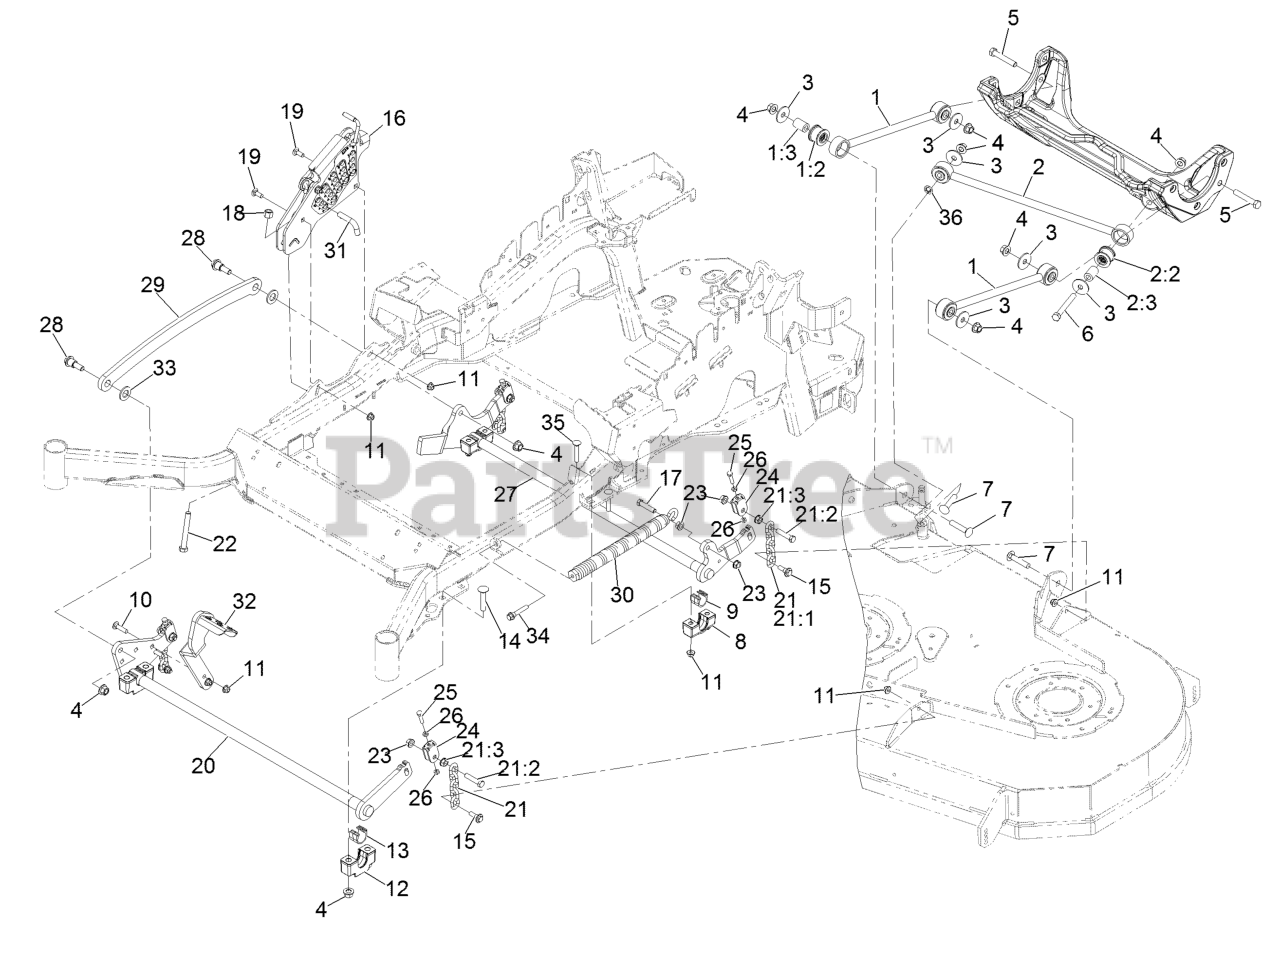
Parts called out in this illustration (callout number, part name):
1	DECK STRUT ASM
1:2	BUSHING-SUSPENSION, RUBBER
2	PANHARD ROD ASM
2:2	BUSHING-SUSPENSION, RUBBER
3	WASHER-THRUST
4	Nut-Lock 1/2-13
5	SCREW-HH
6	SCREW-HH
7	SCREW-CARR
8	SUPPORT-CROSS SHAFT, BEARING REAR
9	BEARING-CROSS SHAFT, REAR
10	SCREW-CARR
11	NUT-HF, NI
12	SUPPORT-CROSS SHAFT, BEARING
13	BEARING-CROSS SHAFT, FRON
14	Bolt-Carriage 1/2-13 X 2 1/2 Spl Neck
15	SCREW-SHOULDER, HHF
16	HOC ASM
17	SCREW-HH
18	NUT-LOCK, NI
19	BOLT-CARR
20	DECKLIFT-FRONT
21	DECK LIFT CHAIN ASM
21:1	CHAIN-LIFT, DECK
21:2	SCREW-HH
22	BOLT-TAP
24	YOKE-ADJUST, DECK
25	SCREW-HH
26	NUT-JAM
27	LIFT-DECK, REAR
28	SCREW-SHOULDER, HHF 1/2-13 X 1.12
29	LINK-LIFT, DECK
30	SPRING-EXTENSION
31	PIN-HOC
32	LEVER-FOOT
33	WASHER-FLAT
34	BOLT-SHOULDER
35	Bolt-Carriage 3/8-16 X 2 1/4
36	NUT-PUSH
